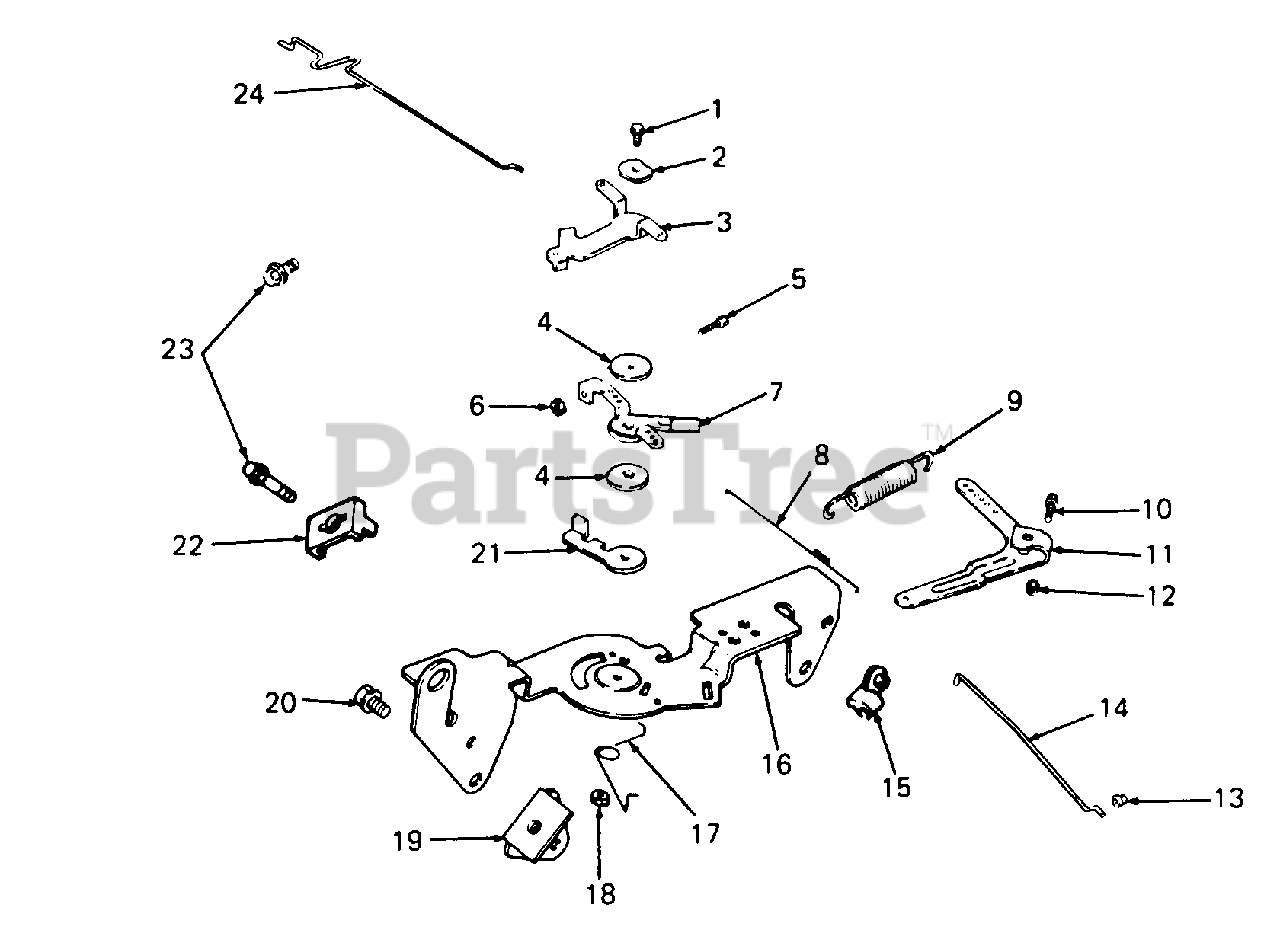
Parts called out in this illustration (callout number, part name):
1	Screw, M5 x 0.8 x 20
2	Washer, Spring
3	Lever, Choke
5	Screw, M4 x 0.7 x 27.9
6	Nut
7	Lever, Throttle Control
8	Spring, Linkage
9	Spring, Governor
10	Screw, M6 x 1.0 x 25
11	Lever, Governor
12	Nut, M6 x 1.0
13	Bushing, Linkage Retaining
14	Linkage, Throttle
15	Bushing, Linkage Retaining
16	Bracket, Control
17	Spring, Choke Return
18	Nut, M5 x 0.8
19	Bracket, Support
20	Screw, M6 x 1.0 x 16
21	Lever, Throttle Actuator
22	Clamp, Cable
23	Screw, M5 x 0.8 x 16
24	Linkage, Choke
